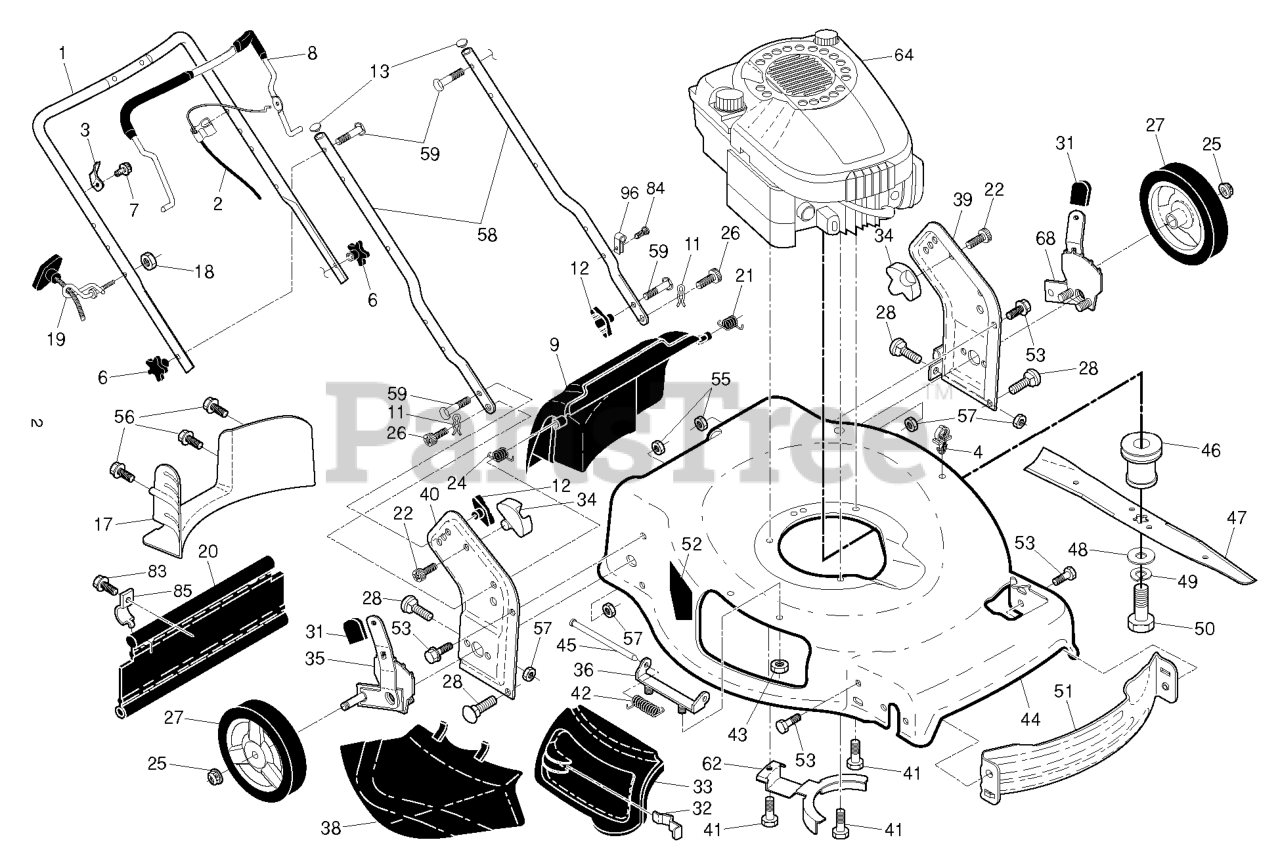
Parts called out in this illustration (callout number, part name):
1	HANDLE.UP.DST.SS/VS.FG/RGD.CRE
2	CABLE.MZR.FGD.PLUS
3	BRACKET.UPSTOP.RT
6	KNOB.HANDLE.PLASTIC.STAR.BLACK
8	RP BAIL.OVER.MOLD.STRAIGHT.ORG
9	DOOR.REAR.ASM.22+.HUSQ.FG/RGD
11	COTTER.HAIRPIN.DOOR/HANDLE.PIV
12	KNOB, DEFLECTOR
13	PLUG.PLASTIC.7/8".14-20.GAUGE
17	BAFFLE.22PLUS.FGD.REAR.
18	NUT
19	RB GUIDE.ROPE.STD.BLK.ZIN WSL
20	SKIRT.REAR.22PLUS.RGD/FGD.NEW
21	SPRING.LH.BLACK
22	SCREW.PAN.HEAD.#10
24	SPRING.RH.GRAY
25	NUT.HEX.FLANGE.3/8-16.LOCKNUT
26	SCREW,DOOR/HANDLE.PIVOT
27	WHEEL & TIRES ASSY, FRONT
28	BOLT
31	SELECTOR KNOB
32	LATCH.DOOR.ZINC
33	DOOR.MULCH.22 PLUS.HUSQ.GREY
34	BRACKET.GRASSBAG.ATTACHING.BLK
35	ADJUSTER.ASM.9POS.LW.RR/RGD.
36	BRACKET.ASM.HINGE.21.FWGD.
38	DEFLECTOR.CLIPPING.22.BLACK
39	BRACKET.ASM.HNDL.LT.22+.GREY
40	BRACKET.ASM.HNDL.RT.22+.GREY
41	BOLT 3/8-16X1-1/8
42	SPRING.TORSION
43	NUT.HEX.FLANGE.1/4
44	HOUSING.22+.FWD.MC.ZWO.ORANGE.
45	ROD.HINGE.21
46	ADPTER.BLAD.25M.VS.22PLU.STAR
47	BLADE.22+4N1.2PIN.5STAR.(P07)
48	WASHER,HARDEN
49	LOCKWASHER
50	SCREW, HEX HD 3/8-24 X 1-3/8
51	BAFFLE.FRONT.22.PLUS
52	DANGER DECAL
53	BOLT.5/16HEX.WHS.HD
55	NUT.HEX.FLANGE.1/4
56	SCREW.HX.13X.750
57	NUT.FLANGE.5/16
58	HANDLE.LOWER.22+BT.2PC.GRY
59	BOLT, HANDLE 5/16-18X1.75
62	BRACKET.ENG/BELTKEEPER
68	ADJUSTER.ASM.9POS.LW.RL/RGD.FR
83	TAPPING SCREW
84	FASTENER.PUSH.O.250X0.783
85	BRACKET.SKIRT.22+.BZP
96	CLIP.CABLE.BLK
